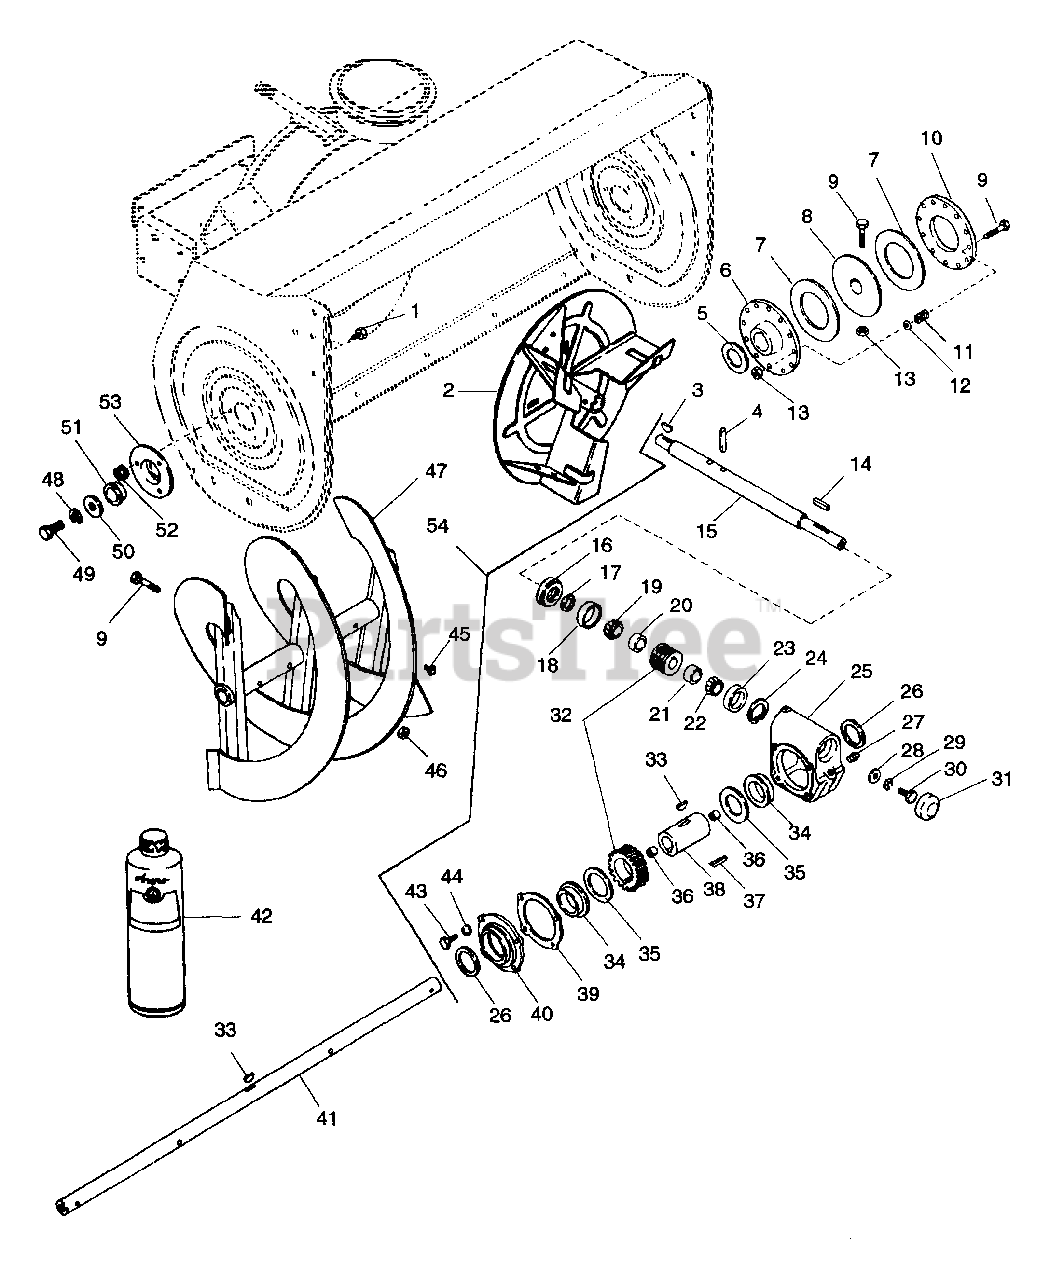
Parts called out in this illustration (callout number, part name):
1	BLT-SERNK SL .25-20X.50 PL
2	FAN 16 INCH
3	KEY-WDRF .188X.875X.375 SAE11
4	PIN-ROLL .313X1.75
5	WSHR-FL-NYL 1.625X2.500X.060
7	FRICTION DISC
8	DRIVEN PLATE
9	BLT-HEX .31-18X2.00 PL GR5
10	PRESSURE PLATE
11	SG-COMP .156X.665X.75
12	WSHR-FL-STL .323X.625X.062 PL
13	NUT-LK-TOP .312-18 GR C PL
14	KEY-SQ .188X1.0X.188 SAE 8630
15	SHFT,WORM
16	ADJUSTMENT PLUG
17	SEAL 1.125X1.375X.125
18	BRG-CUP1.980X.420
19	BRG-CONE 1.0X.58
20	BEARING SPACER 1.032X1.25X1.78
21	BSHG, SPCR .755X1.12X.50 PM
22	BRG-CONE .750X.61
23	BRG-CUP 1.781X.475
24	RG-RTNG-INT 1.781X.062
25	GEAR CASE - CAST IRON
26	SEAL 1.625X2.125X.250
27	PIPE PLUG
28	WSHR-FL-STL .328X1.0X.094 PL
29	WSHR-LK .312X.097 PL HVY
30	BLT-HEX .31-18X.75 PL GR2
31	DUST CAP
32	WORM & GEAR SERVICE ASSEMBLY
33	KEY-FTHR .25X.875X.25 SAE 8630
34	BSHG-FLG .683X1.87X1.68X2.250
35	WSHR-FL-STL 1.625X2.500X.012
36	BSHG-SLV 1.125X1.250X1.000
37	KEY-SQ .25X.625X.375
38	GEAR CASE SHAFT
40	GEAR CASE COVER
41	40 INCH RAKE SHAFT
42	ARIENS 16 OZ.BOTTLE OF L2 LUBE
43	BLT-HEX .25-20X.75 PL GR2
44	WSHR-LK-EXT. 250 ID
45	FTG-LUBE .25-28X.256 YWZC
46	NUT-LK .312-18 GR A PL
47	RAKE, LEFT-40"(1.12ID X 15.75)
47	RAKE, RIGHT-40(1.12ID X 15.75)
48	WSHR-LK .500X.151 HVY PL
49	BLT-HEX .50-13X1.00 PL GR2
50	WSHR-FL-STL .511X1.441X.125 PL
51	BSHG-FLG 1.000X1.12X.62X1.50BR
52	NUT-LK-FLG .250-20 PL
53	BEARING SUPPORT
54	GEAR CASE -16" IMPELLER - C.I.
